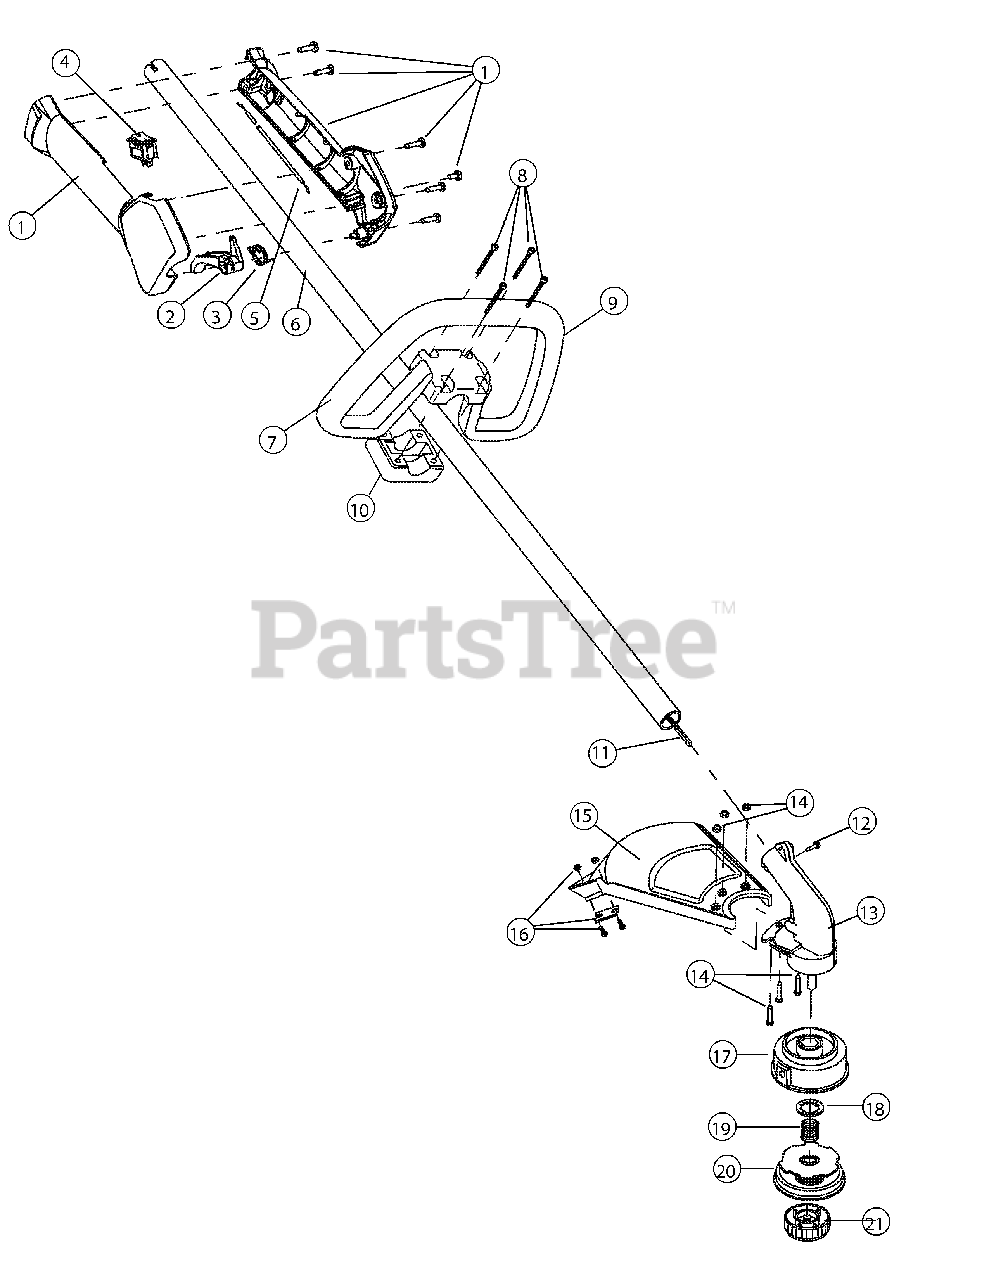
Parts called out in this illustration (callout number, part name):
1	Throttle Housing Assembly
2	Throttle Trigger
3	Throttle Trigger Spring
5	Throttle Cable Assembly
6	Upper Drive Shaft Housing Assembly
7	Deluxe D-Handle Assembly
9	Deluxe D-Handle
10	Bottom Clamp
11	Flexible Drive Shaft
12	Anti-Rotation Screw
13	Gear Box Assembly
14	Shield Mounting Hardware
15	Shield Assembly
16	Blade Assembly
17	Outer Spool Assembly
20	Inner Reel
21	Bump Head Knob Assembly
